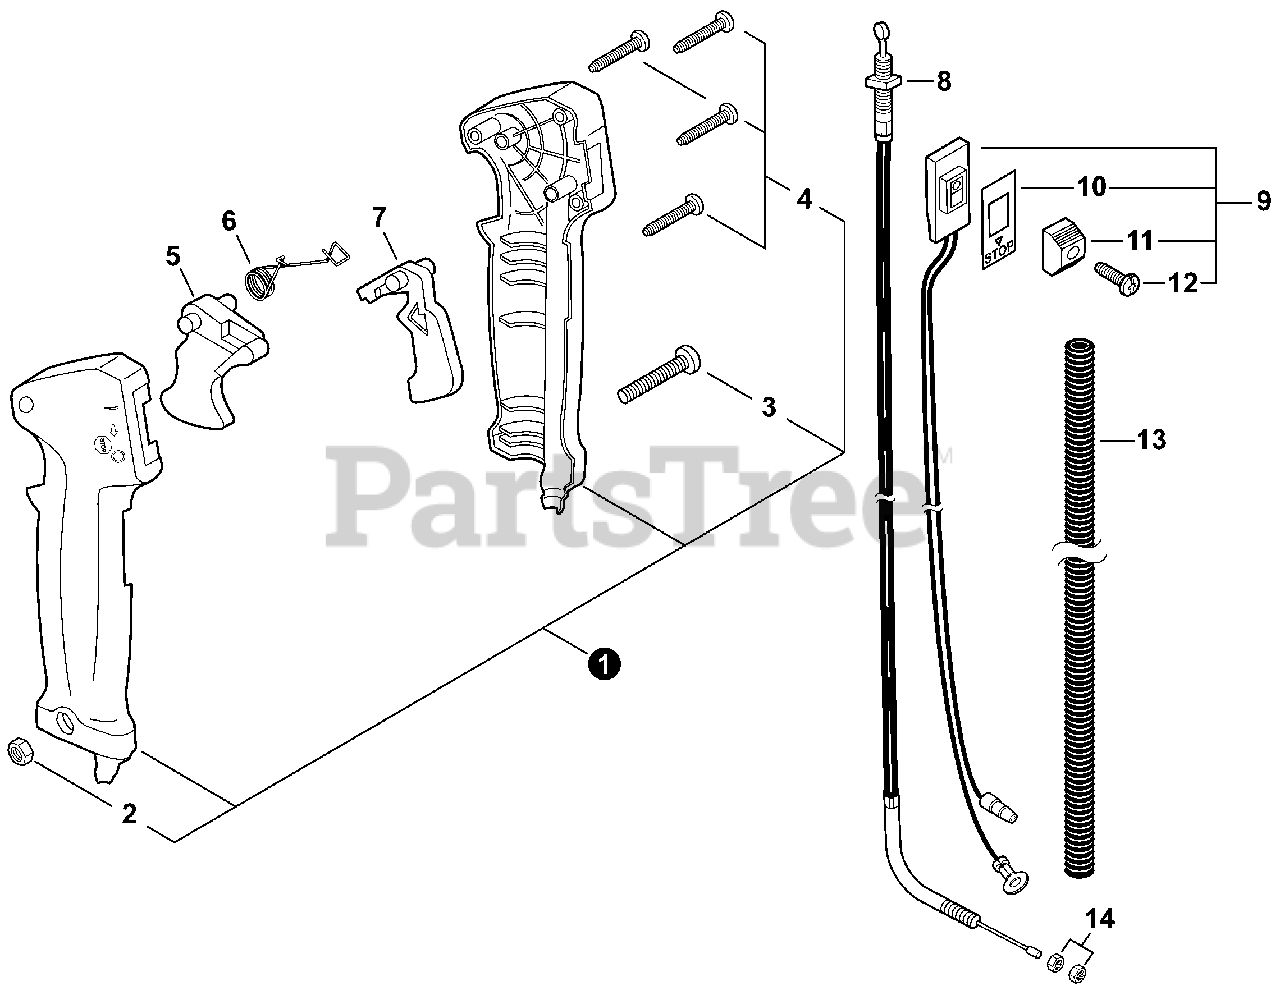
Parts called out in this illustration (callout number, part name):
1	CONTROL HANDLE KIT
2	NUT M5
3	SCREW 5×30
4	SCREW 3×25
5	TRIGGER, THROTTLE
6	SPRING, TORSION
7	LOCKOUT, THROTTLE
8	CABLE, THROTTLE
9	SWITCH, ON-OFF
10	LABEL, SWITCH
11	KNOB, SWITCH - ORANGE
12	SCREW 3×10
13	TUBE, FLEXIBLE 7×820
